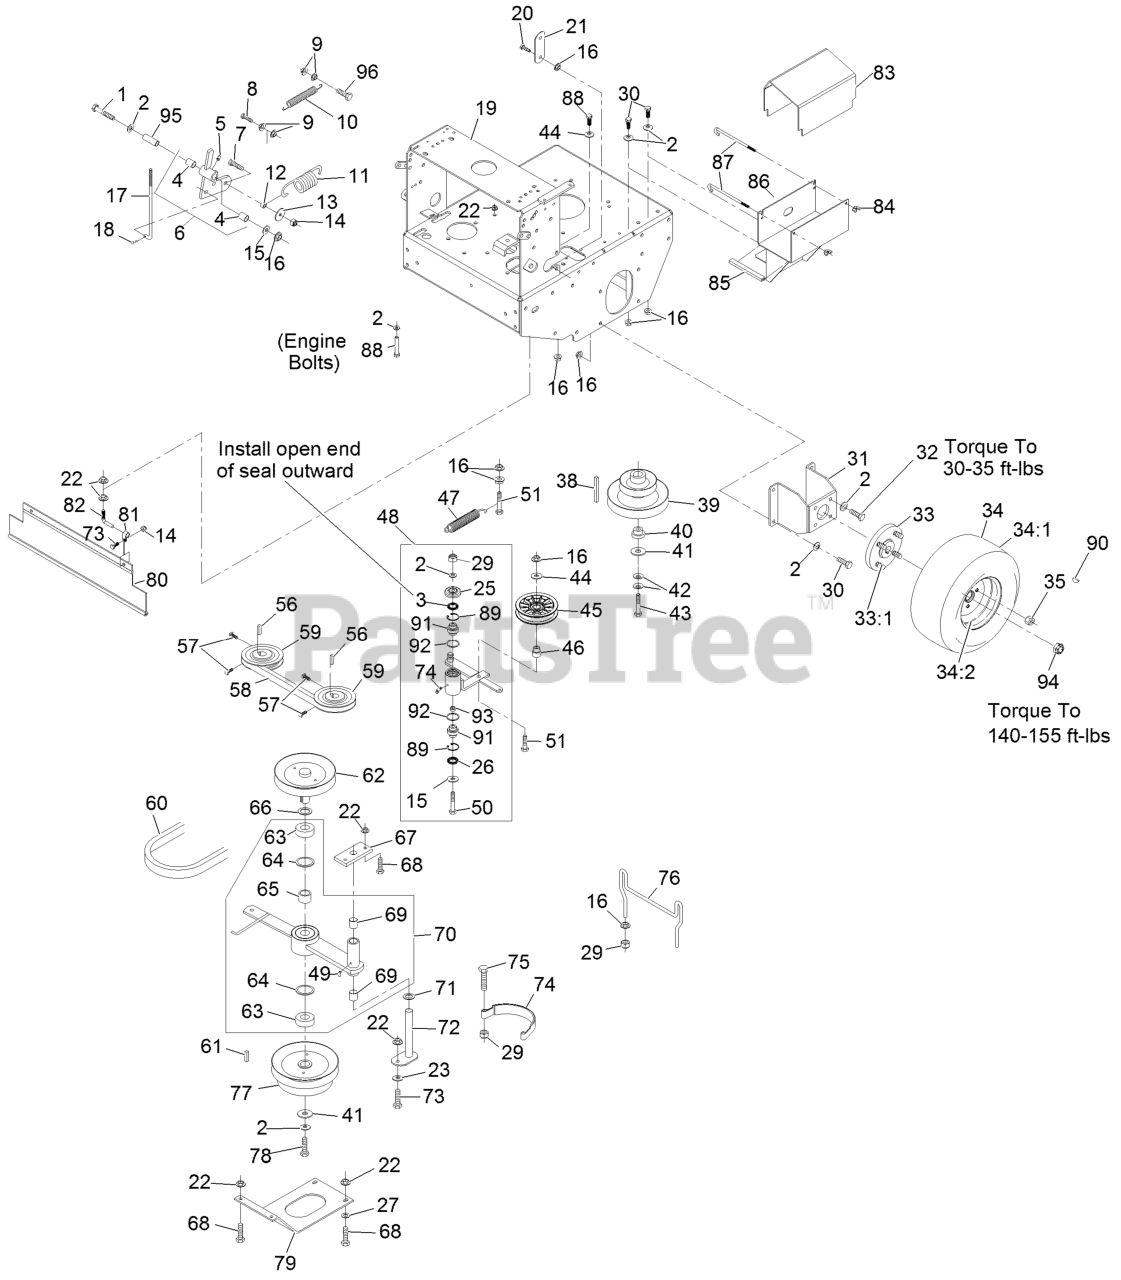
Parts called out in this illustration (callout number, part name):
1	SCREW-HH
2	WASHER-BELLEVILLE
3	SEAL-LIP, SINGLE
4	SLEEVE-BEARING
5	FITTING-GREASE
6	ASM,PIVOT W/BUSHINGS
7	SCREW-HH
8	SCREW-HH
10	SPRING,EXTENSION
11	SPRING,EXTENSION
12	SPACER,CLUTCH ANCHOR
14	NUT-LOCK, NI
15	WASHER-FLAT
16	NUT-HHF, WHIZ
17	LINKAGE,LOWER
18	PIN-COTTER
19	KIT, TTS ENG DECK
20	SCREW-HH
21	ARM-LIFT, DECK
23	WASHER-SPRING
25	GUARD-TOP
26	SEAL-LIP, DOUBLE
27	WASHER-FLAT
29	NUT-LOCK, NI
30	SCREW-HH
31	WLD,MOTOR MOUNT 48&52
32	SCREW-HH
33	WHEEL HUB ASM
33:1	STUD-WHEEL
34	WHEEL AND TIRE ASM
34:1	TIRE-TURFMASTER
34:2	RIM-WHEEL
35	NUT-LUG
38	KEY,MACH 1/4X1/4X2-5/8
39	SHEAVE, DRIVE
40	BUSHING,CLUTCH KEEPER
42	WASHER-SPRING
43	SCREW-HH
44	WASHER-FLAT
45	PULLEY-IDLER, FLAT
46	BUSHING-IDLER
48	KIT,PUMP IDLER ARM TTHP
49	FITTING-GREASE
50	SCREW-HH
51	SCREW-HH
57	SCREW-SET, SQH
58	BELT,COG A 50.55
59	SHEAVE ASM
60	BELT,B-38.0
62	SHEAVE, W/ SHAFT
63	BEARING,CLUTCH SHAFT
64	RING-SNAP
65	SPACER,CLUTCH BEARING
66	WASHER-SPACER
67	PLATE-CLUTCH PIVOT
68	SCREW-HH
69	SLEEVE,BEARING
70	ASM,CLUTCH ARM W/BEARING
71	WASHER-SPACER
72	WLD,PIN PIVOT
73	SCREW-HH
74	BAND,BRAKE BLADE
75	SCREW-HH
76	GUIDE,BELT (PLTD)
77	SHEAVE,6.75 W/DRUM
78	SCRW,CAP HH
79	PLATE-GUARD
80	SHIELD-DRAG
81	CLIP-LOOM
82	MOUNT,DRAG SHIELD
83	COVER,BATTERY W/DECAL
84	WINGNUT
85	TRIM-LOK
86	ASM,BATTERY STAND W/TRIM
87	BOLT - HOLD DOWN
88	SCREW-HH
89	RING-SNAP
90	KEY-WOODRUFF
91	BEARING-SPHERICAL
94	NUT-LOCK
95	BUSHING
96	SCREW-HH
